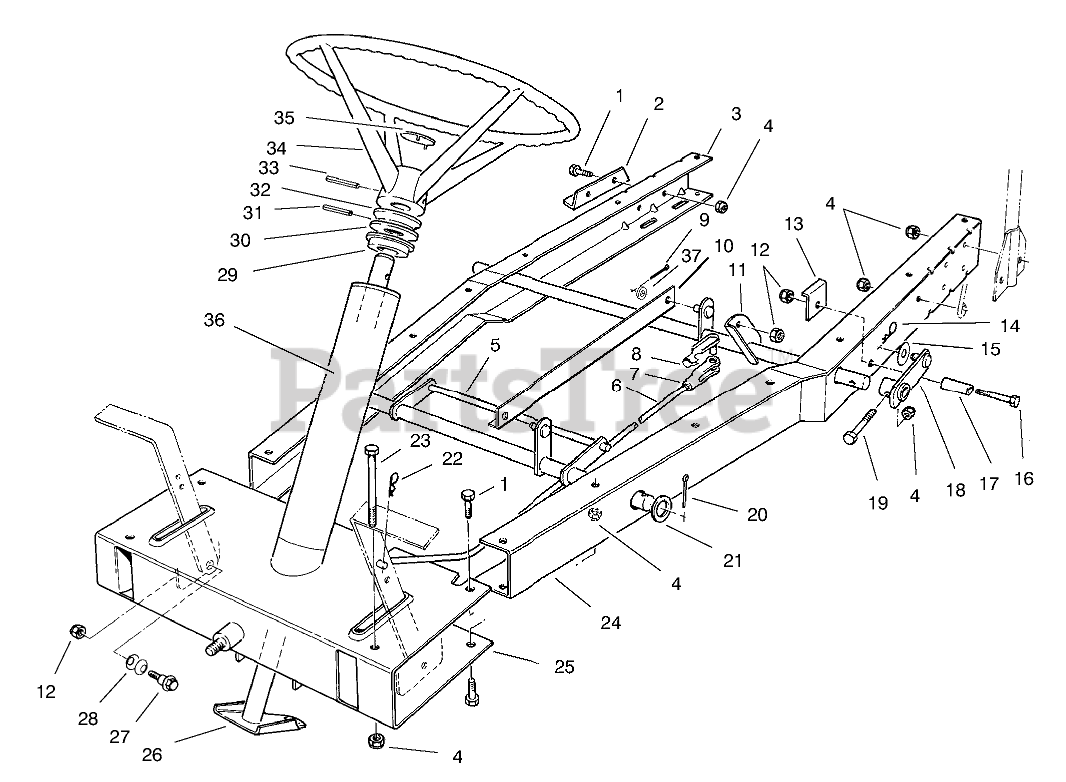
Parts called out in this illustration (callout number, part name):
1	SCREW-HH
2	MOUNT-AXLE BRG
3	FRAME-CHANNEL RH RED
4	NUT-LOCK, NI
5	FRT DECK LIFT WA BLACK
6	ROD-CLUTCH
7	CLEVIS-ADJ
8	CLEVIS PIN ASM
9	PIN-COTTER
10	LINK-HOC BRACKET
11	REAR SUP TUBE WA RED
12	NUT-LOCK, NI
13	DECK STOP BRACE (BLACK)
14	PIN-HAIR
15	WASHER
16	SCREW-HH
17	SPACER-STOP,DECK
18	HOC LEVER WA
19	AXLE MTG BOLT
20	PIN-COTTER
21	WASHER-FLAT
22	PIN-COTTER
23	SCREW-HH
24	FRAME-CHANNEL LH
25	FRONT FRAME WA RED
26	STEERING SHAFT WA BLK
27	BOLT-SHOULDER
28	WASHER-BELLEVILLE
29	BUSHING-STEERING
30	WASHER-STEERING
31	PIN-ROLL
32	SPACER-STEERING
33	PIN-ROLL
34	STEERING WHEEL ASM
35	INSERT - STRG WHL F/W
36	DECAL - STEERING COLUMN
37	WASHER-FLAT
